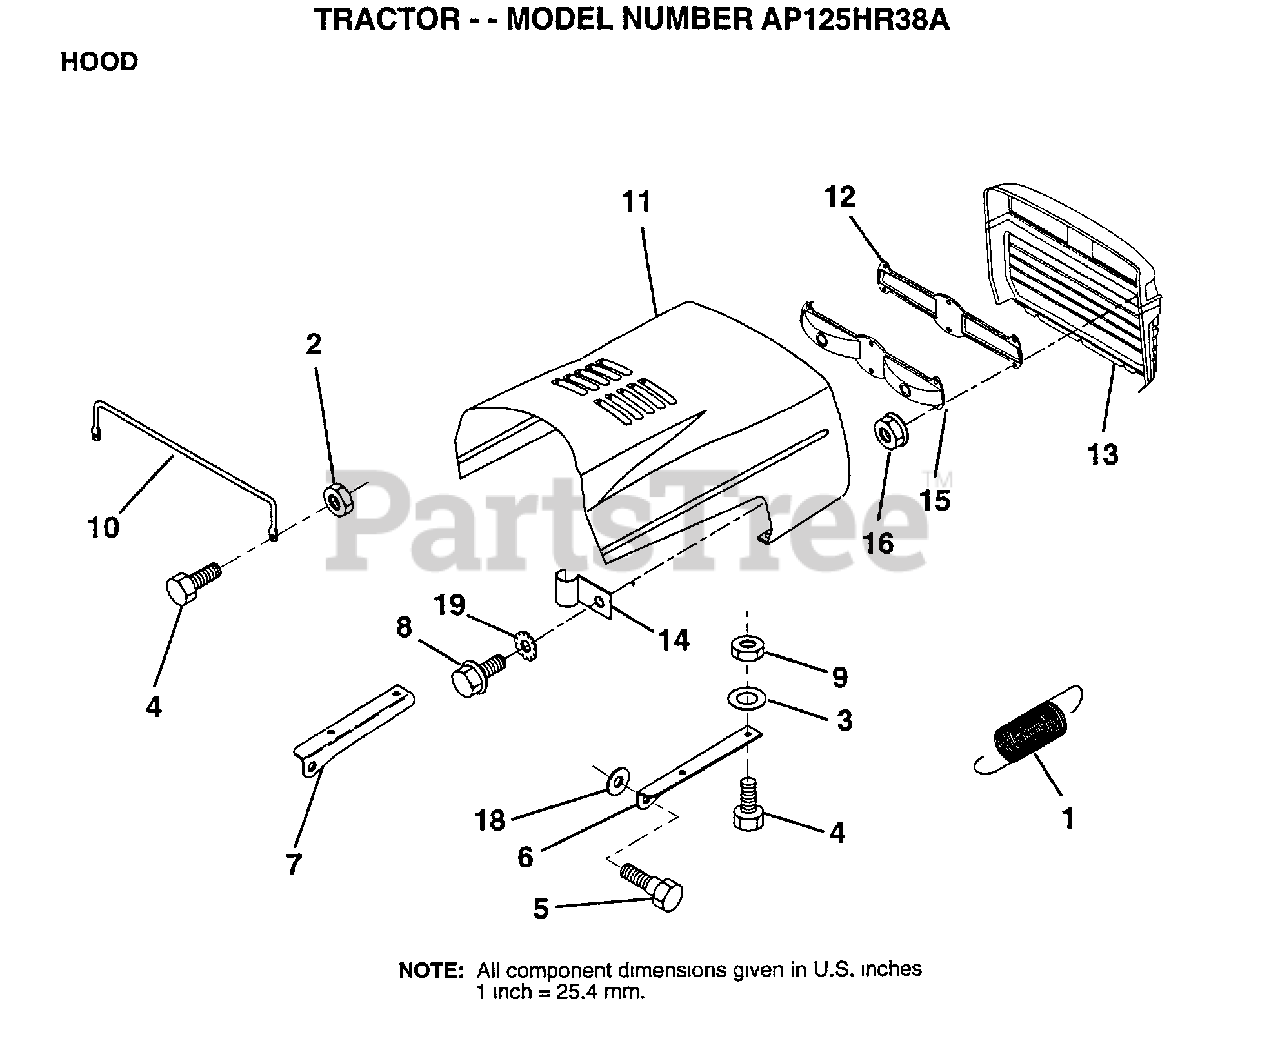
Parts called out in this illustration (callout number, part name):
1	EXT SPRING
2	NUT HXKEP 1/4X20
3	WASHER
5	BOLT.SHLD.5/16-18
6	BRKT HOOD RH
7	BRKT HOOD LH
8	SCREW SLTD HXHD
9	NUT
10	"BRACE,HOOD"
11	HOOD
16	NUT
18	WASHER
19	LOCKWASHER GT
